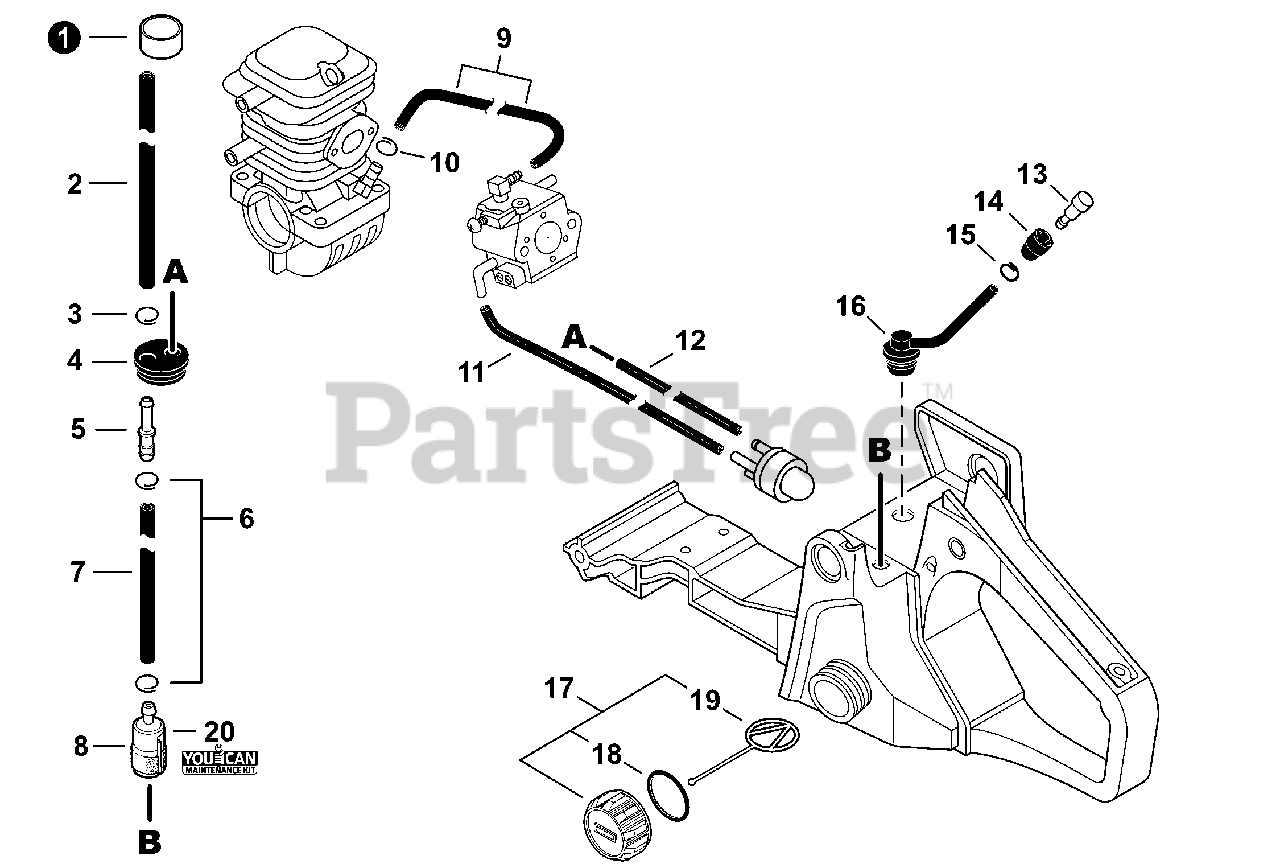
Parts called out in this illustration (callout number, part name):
1	TUBE 8×9×16
2	PIPE, FUEL - 3×5×182 - BLACK
4	GROMMET, FUEL
5	CONNECTOR, PIPE 5×3.5
7	PIPE, FUEL - 3×5×68 - BLACK
8	FILTER, FUEL
9	PIPE, PULSE 2.4×6×105
11	PIPE 2.4×5×105 BLACK
12	PIPE, FUEL 2.4×5×200 BLACK
13	VENT ASSY
14	HOLDER, VENT
15	CLIP 6.5MM
16	PIPE, VENT 3×6×65
17	CAP ASSY, FUEL
18	O-RING 22
19	CONNECTOR, CAP L= 60mm
20	TUNE-UP KIT - YOUCAN™
